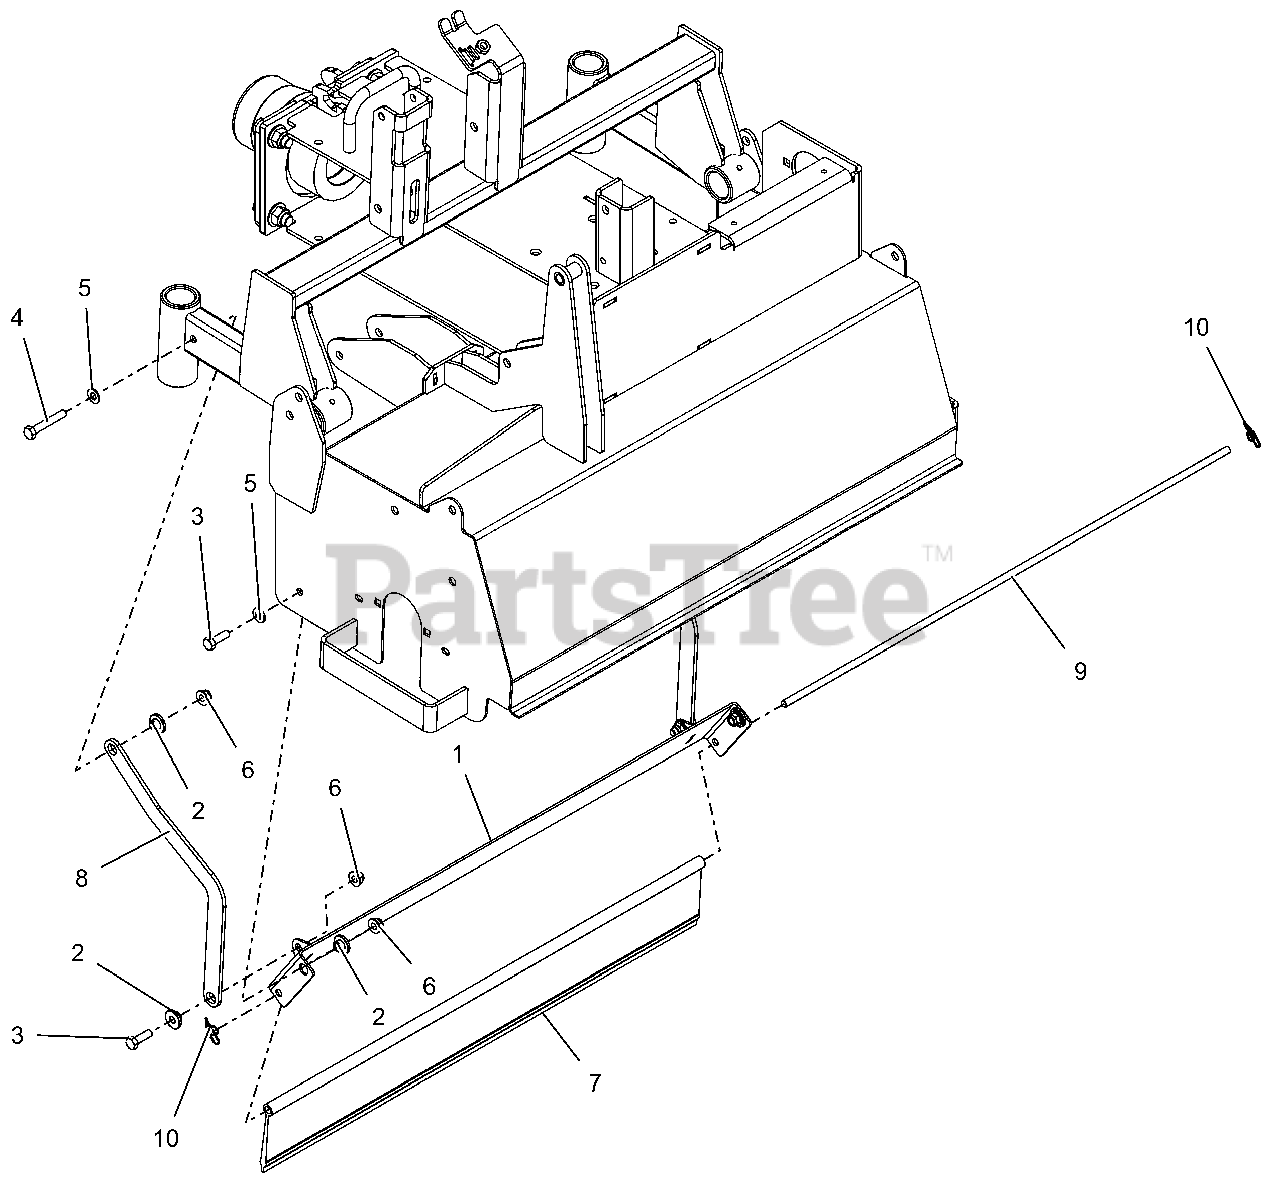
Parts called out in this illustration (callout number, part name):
1	WLDMT, REAR SKIRT CONTROL
2	BSHG-FLG .32X.500X.344X.880
3	BLT,HEX .31-18X1.00 G5 ZCC
4	BLT, HEX .31-18X2.00 G5 ZCC
5	WSHR,FLT .344X.688X.065 ZCC
6	NUT,NYL-FLG .31-18 GF ZCC
7	FLAP, REAR PLASTIC
8	ARM, CONTROL REAR FLAP
9	PLATE, SHIELD PIVOT
10	RING, RUE .375 X .054 X 1.254
